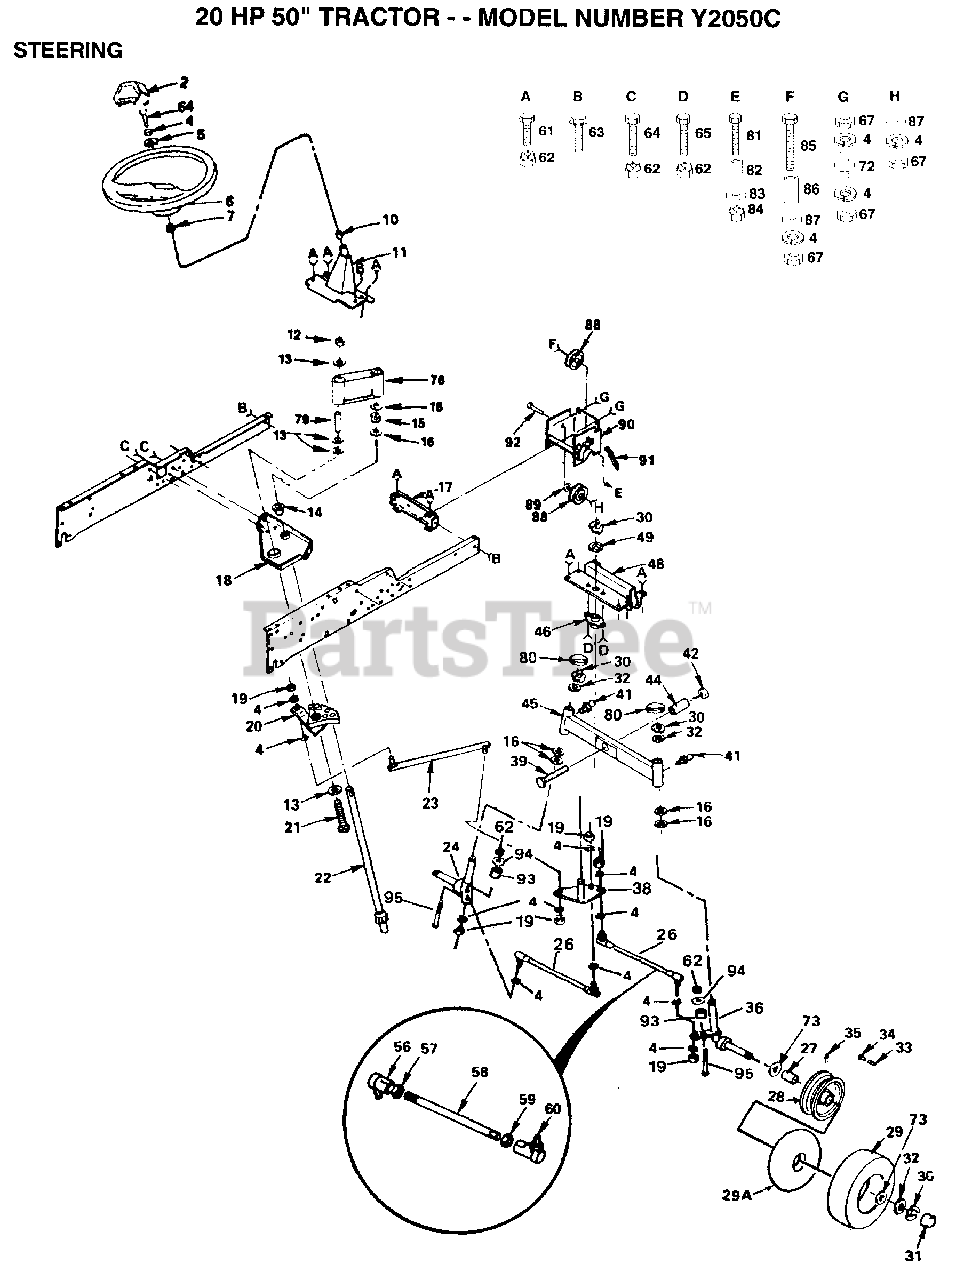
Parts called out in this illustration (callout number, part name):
2	INSERT STEERING
4	LOCKWASHER
5	WASHER T
7	ADAPTER LT
10	"T, BEARING"
11	SUPPORT ASSY T
12	NUT LTV
13	WASHER GT
14	"FLANGE GT, BEAR."
15	KLIP RING
16	WASHER .T
17	FRAME BRACKET GT
20	SECTOR T
21	BOLT T
22	SHAFT STEERING GT
23	LINK.DRAG.T
24	SPINDLE.ASM.LH
26	TIE ROD T
27	"FLANGE, BEARING"
29A	TUBE.16X6.5/7.5-8
30	RING
31	HUB CAP
32	WASHER
33	VALVE CAP
34	VALVE STEM LT
35	FITTING LT
36	SPINDLE.ASM.RH
38	"T, BELLCRANK"
39	BOLT
41	ZERK M
42	LOCKNUT M
44	SPACER BEARING
48	AXLE BRACKET T
49	WASHER
56	JOINT.LH
57	NUT
59	NUT
60	JOINT.RH
63	SCREW
64	BOLT
65	BOLT
67	NUT.HEX.3/8-16UNC
73	WASHER
76	COLLAR
79	TUBE T
80	CAP
82	SPLIT SPACER YTV
83	WASHER
85	BOLT
86	BUSHING LT
87	WASHER
88	IDLER-INSIDE T
89	WASHER T
90	IDLER BRKT T
91	SPRING
93	SPACER LT
94	WASHER T
95	BOLT
